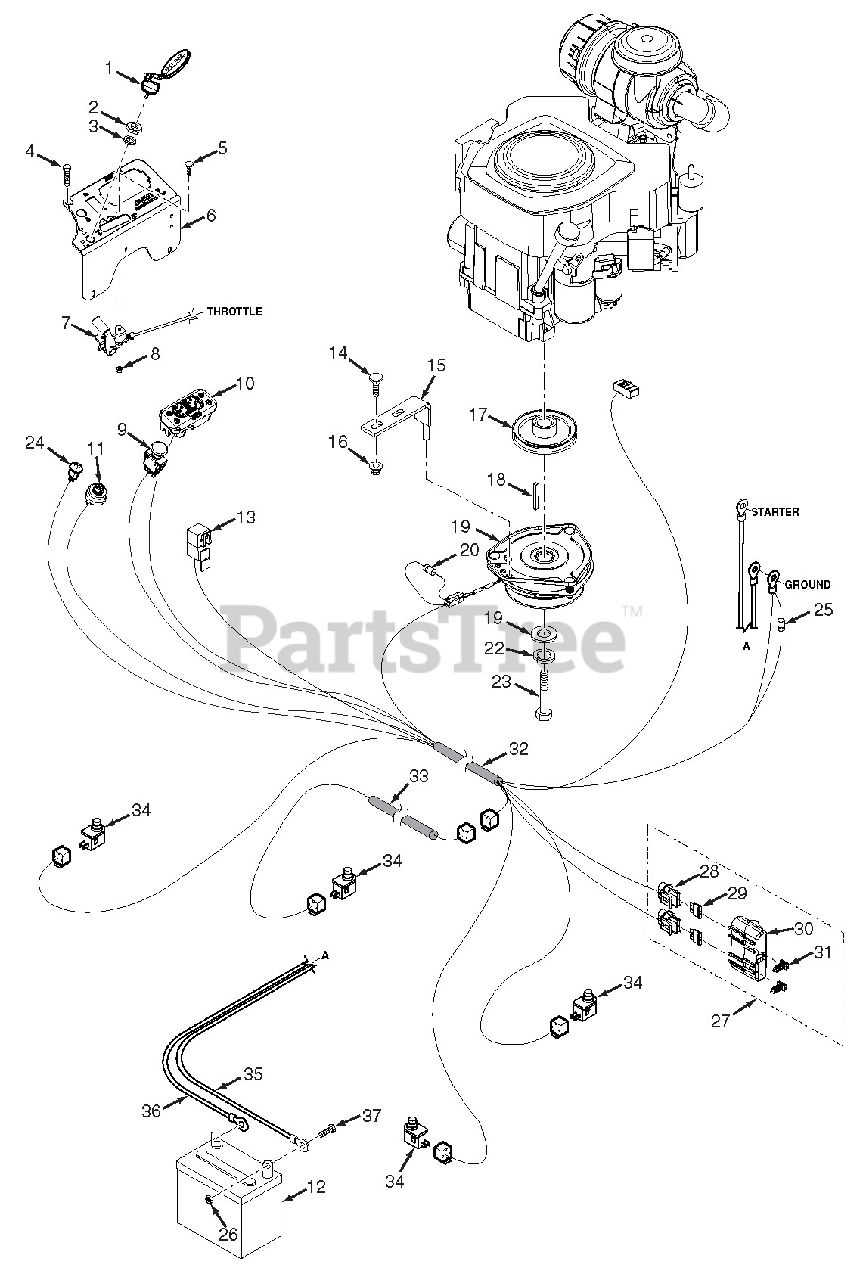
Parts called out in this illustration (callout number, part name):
1	Key, Ignition
1	Key Assembly w/Fob
2	Nut, Hex 5/8-32
3	Lockwasher, 5/8" Internal
4	Bolt, Hex Head Serrated Flange 1/4-20 x 1/2"
5	Bolt, Carriage #10-24 x 1/2"
6	Instrument Panel w/Decal
7	Control Cable
8	Locknut, #10-24
9	Switch, PTO
10	Tiger Eye Cluster Gauge
11	Switch, Starter
12	Battery, 350 CCA
13	Relay
14	Bolt, Carriage 5/16-18 x 3/4"
15	Anti-Rotation Weldment
16	Nut, Flange Elastic Stop 5/16-18
17	Pulley, 5" Dia. - 1.125 Bore
18	Key, 1/4 x 1/4 x 3-1/2"
19	Clutch, GT3.5 - 1.125 Bore
20	Diode, 600V - 6A
21	Flatwasher, 7/16-.469 x 1.75 x .25
22	Lockwasher, 7/16" Spring
23	Bolt, Hex Head 7/16-20 x 2-1/4" w/Patch
24	Indicator Light
25	Diode
26	Nut, 1/4-20 UNC
27	Double Fuse Assy.
28	Fuse Holder
29	Fuse, 20 Amp
30	Cover, Sealed Double
31	Clip, Wire
32	Wire Harness, SCZ-EFI
33	Wire Harness, Operator Platform
34	Switch
35	Battery Cable, 25" Red (Kawasaki)
36	Battery Cable, 27" Black
37	Bolt, Hex Head 1/4-20 x 1/2"
